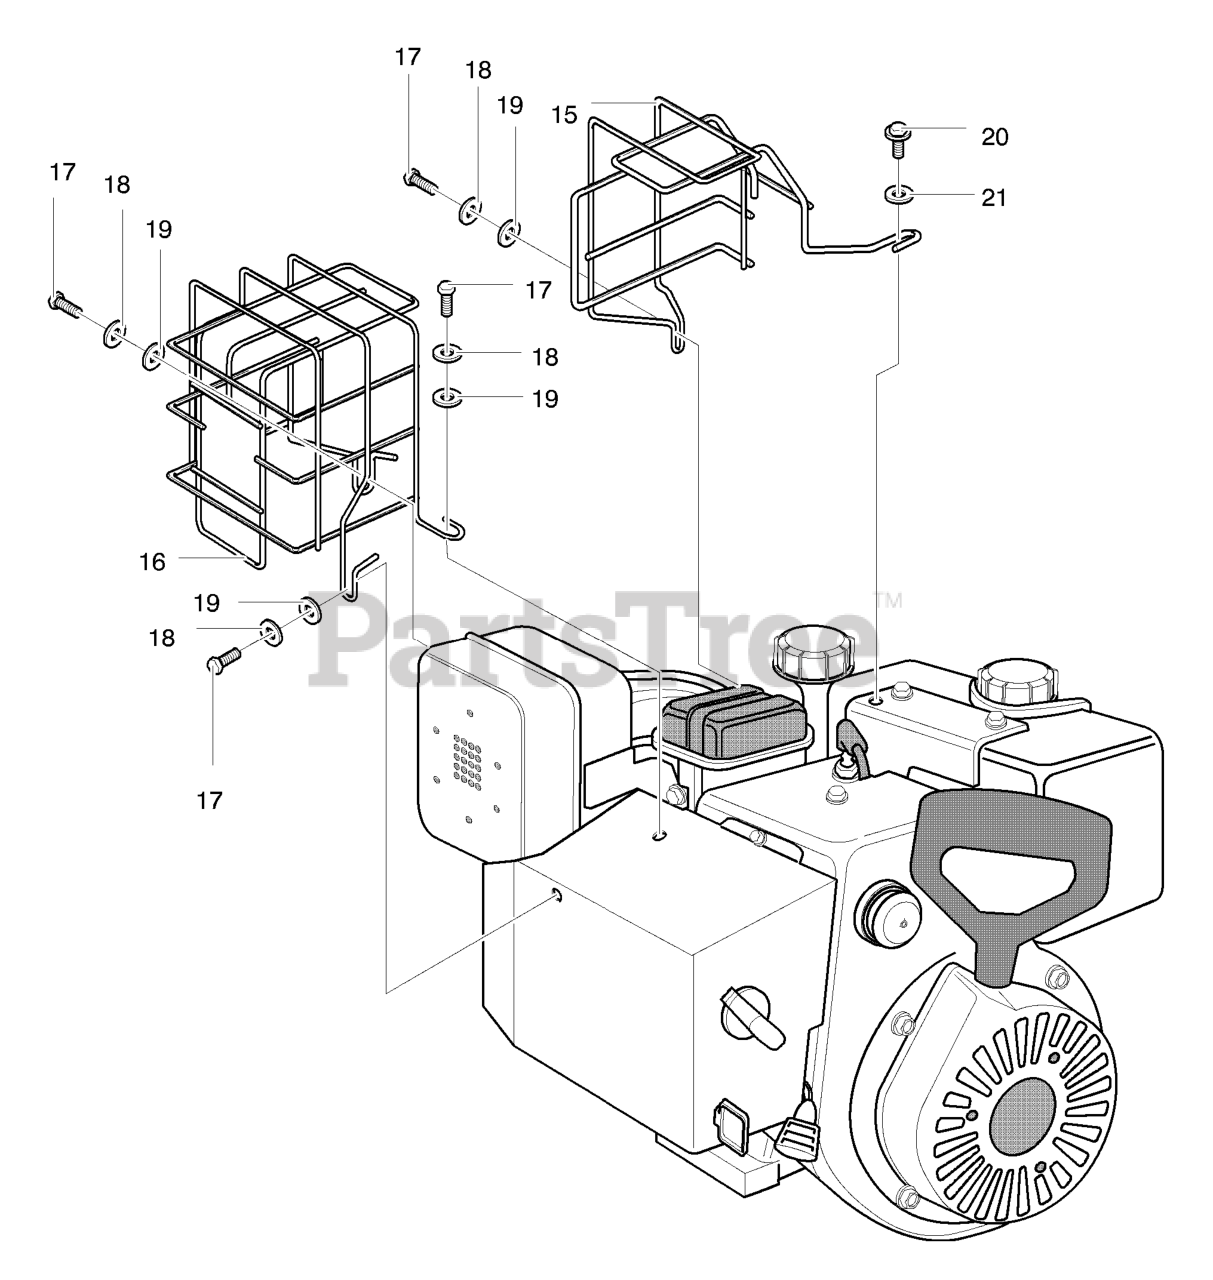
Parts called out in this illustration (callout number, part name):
15	GUARD, RIGHT MUFFLER
16	MOTOR, LEFT STARTER
18	WASHER
19	WASHER
20	SCREW
